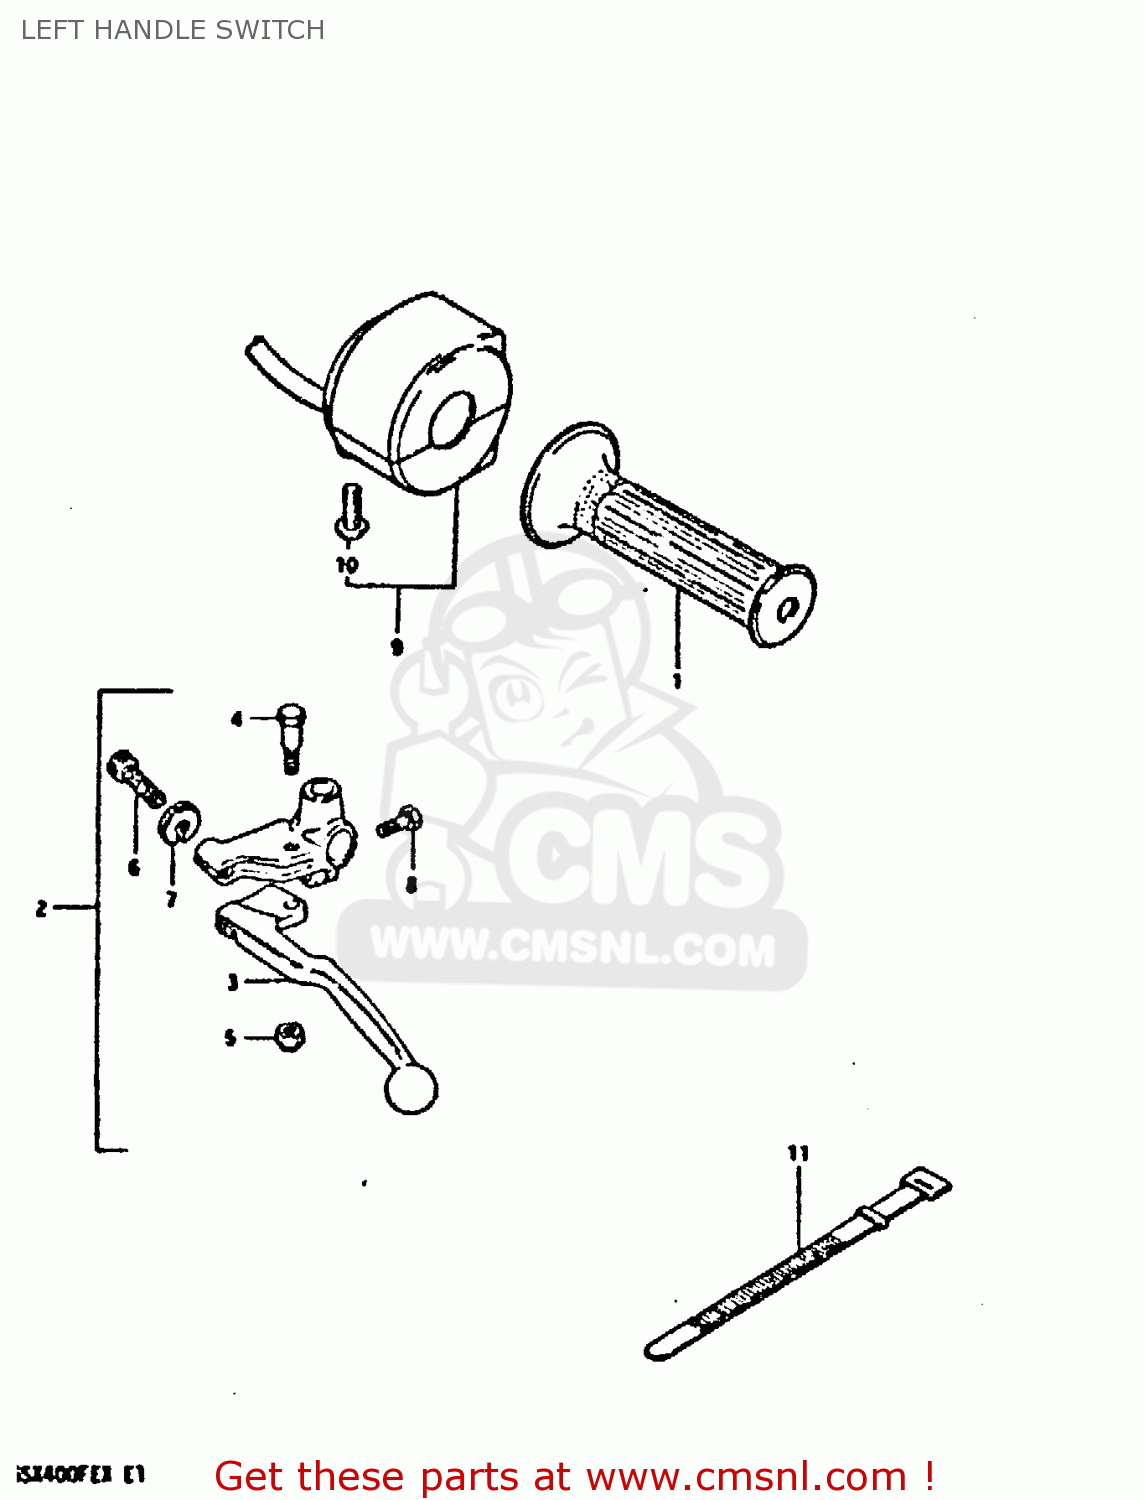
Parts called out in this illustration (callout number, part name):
1	GRIP,LEFT
2	LEVER ASSEMBLY
3	LEVER, CLUTCH
4	BOLT,LEVER
5	NUT 6MM
6	ADJUSTER,CABLE
7	NUT,CABLE ADJUSTER
8	BOLT,CLUTCH LEVER HOLDER
9	SWITCH ASSY, HANDLE LH
10	SCREW
11	CLAMP(L:120)
